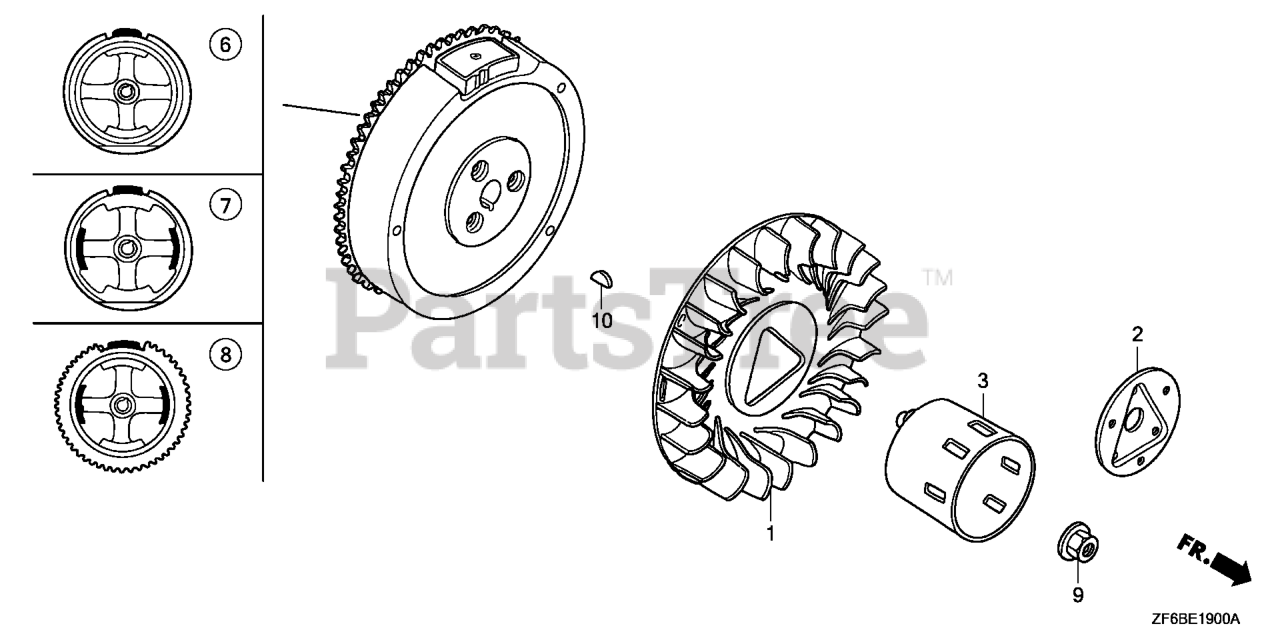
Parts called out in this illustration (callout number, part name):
1	FAN, COOLING
3	PULLEY, STARTER
9	NUT, SPECIAL (16MM) (1)
10	KEY, SPECIAL WOODRUFF (25X18)
